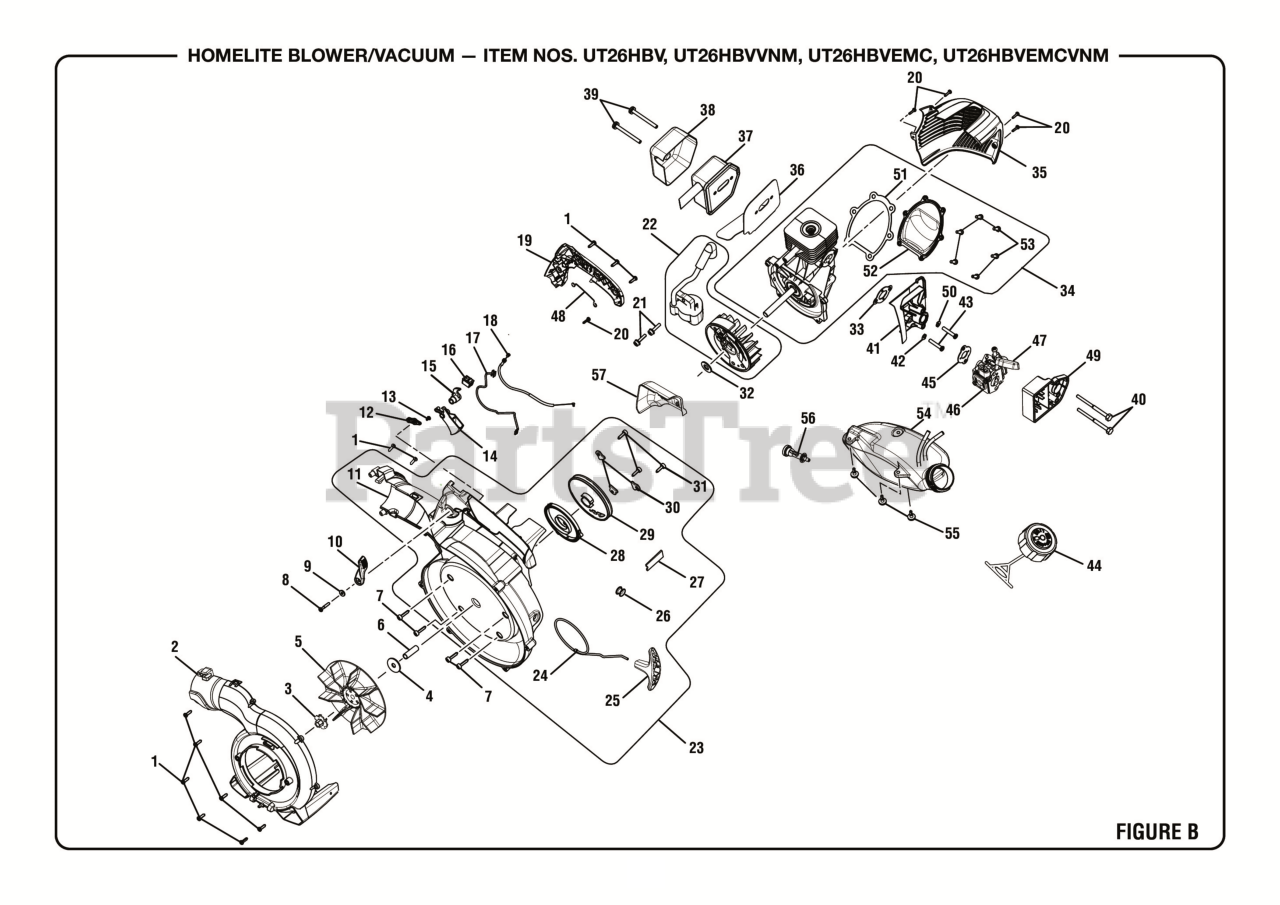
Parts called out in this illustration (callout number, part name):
1	Screw (#10-14 x 3/4 in, T25 Torx Pan Hd. T.F.)
2	Outer Volute w/Labels
3	Lock Nut (3/8 in.)
4	Washer (ID9.8 x OD30 x 3t)
7	Screw w/Washer (M4 x 16 mm, T25 Torx Truss Hd.)
8	Cruise Lever Screw (M8-14 x 25 mm, Special T20 Truss Hd.)
9	Washer (ID 4.3 x OD12 x 1.5t)
10	Cruise Control Lever
11	Inner Volute w/Eyelet w/Label
12	Throttle Lever
13	Screw (M3.5 x 7.5 mm, T20 Torx Pan Hd.)
14	Throttle Trigger
15	Trigger Lock
16	Stop Switch (Momentary Contact)
17	Wire Assembly (UT26HBV)
18	Throttle Cable
19	Handle Cover
20	Screw (M4 x 18 mm, T20 Torx Pan Hd. S.T.)
21	Screw w/Washer (M4 x 19 mm, T20 Torx Pan Hd. S.T.)
22	Ignition Module and Flywheel Kit (UT26HBV)
23	Lower Housing w/Starter and Label
24	Starter Rope (42 in.)
25	Pulley Handle
28	Spring & Container Assembly
29	Starter Pulley
30	Pulley Retainer
31	Screw (M4 x 14 mm, T20 Torx Truss Hd T.F.)
32	Washer (ID9.70 x OD20 x 1.59t)
33	Inner Heat Dam Gasket
34	Short Block Assembly
35	Engine Cover w/Labels
36	Muffler Gasket
37	Muffler Assembly
38	Muffler Heat Shield
39	Screw w/Washers (10-24 x 2-1/8 in., T25 Torx Truss Hd.)
40	Bolt (M5 x 48 mm, T20 Torx hd.)
42	Washer (ID5 x OD10.9 x 0.5t)
43	Screw (M5 x 25 mm, T20 Torx Hd.)
44	Fuel Cap Assembly (Inc. Tether)
45	Heat Dam Gasket
46	Carburetor
47	Primer Bulb (Ruixing)
48	Ground Wire Assembly
49	Air Box Base
51	Crankcase Cover Gasket
52	Crankcase Cover
53	Screw (M4 x 12 mm, T20 Torx Hd.)
54	Fuel Tank Assembly (Inc. Fuel Lines)
55	Shoulder Screw w/Washer (M4 x 14 mm, T25 Torx Truss Hd.)
56	Fuel Filter
57	Baffle Plate
